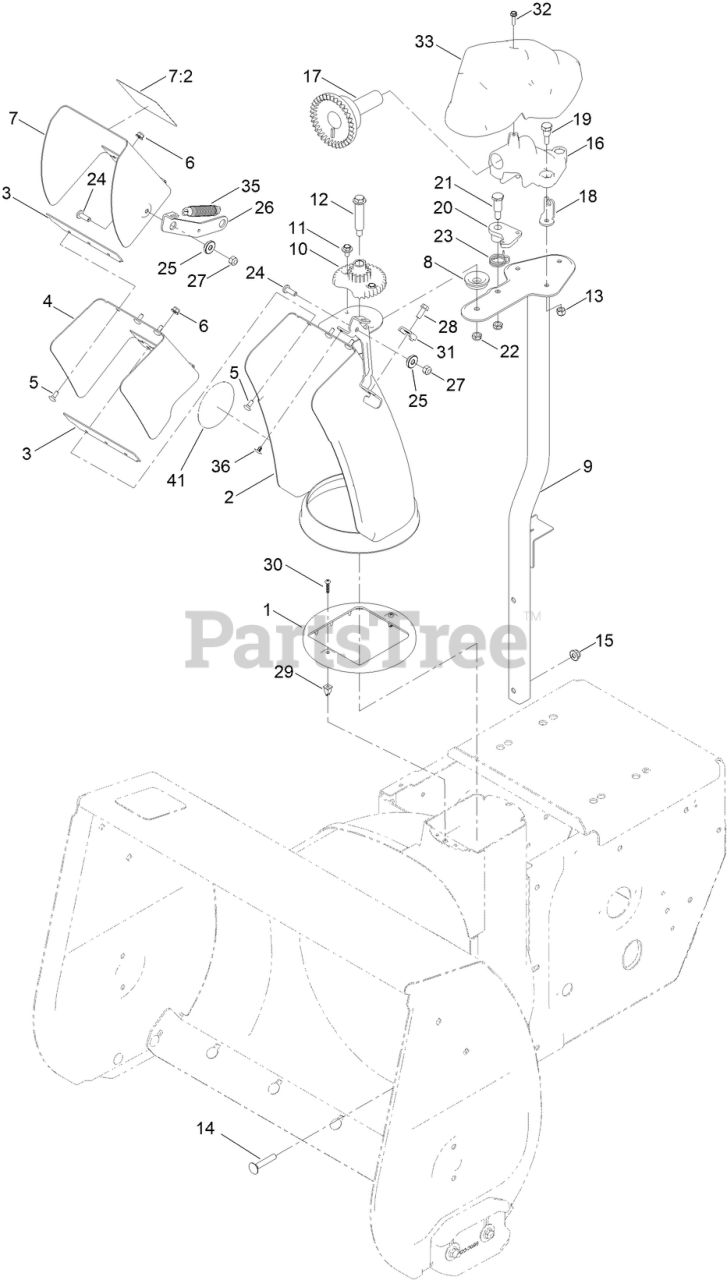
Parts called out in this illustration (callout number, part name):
1	GUIDE-CHUTE
2	LOWER CHUTE ASM
3	GASKET-DEFLECTOR
4	MIDDLE DEFLECTOR ASM
5	BOLT-CARR
6	NUT-HF
7	DEFLECTOR ASM
7:2	DECAL-DANGER
8	SPACER-CHUTE
9	CHUTE POST ASM
10	GEAR-CHUTE
11	SCREW AND WASHER ASM
12	BOLT-SHOULDER
13	NUT-HEX
14	BOLT-CAR
15	NUT-HF
16	MOUNT-GEAR, FACE
17	GEAR-FACE
18	ANCHOR-CABLE
19	SCREW-SHOULDER
20	LATCH-CHUTE
21	SCREW-SHOULDER, HH
22	NUT-HEX
23	SPRING-TORSION
24	SCREW-PH
25	BUSHING-PIVOT
26	LINK-DEFLECTOR
27	NUT-HEX
28	SCREW-HWH
29	GROMMET-SCREW
30	SCREW-PPH
31	CLAMP-CABLE
32	SCREW-PLASTITE, HWH
33	COVER-GEAR, FACE
35	SPRING-EXTENSION
36	PLUG-PLASTIC
41	DECAL - ANTI-CLOG
